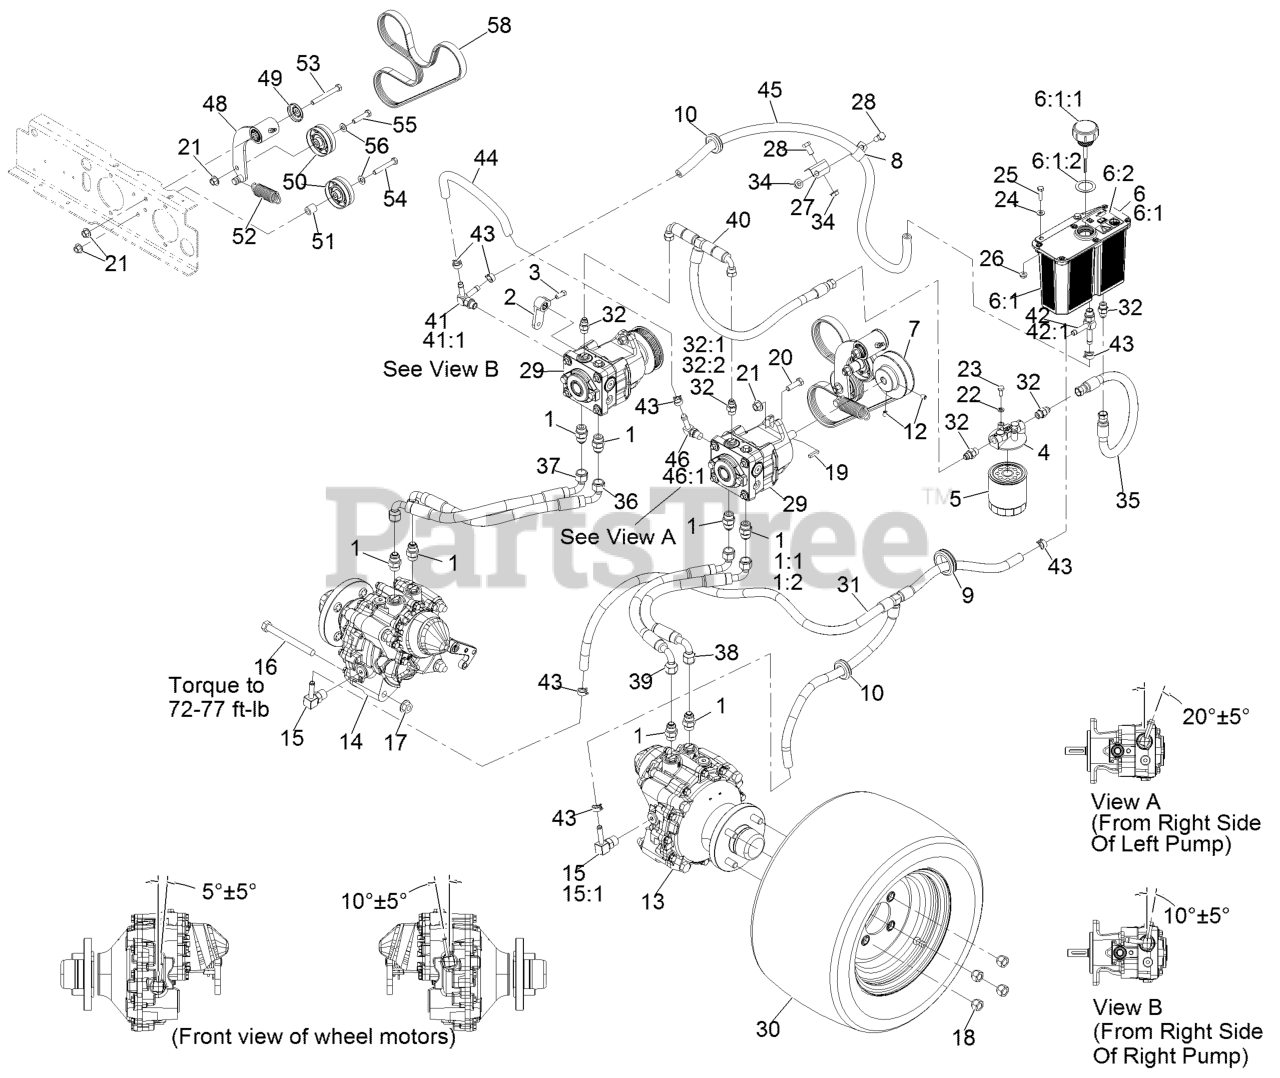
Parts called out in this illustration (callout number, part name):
1	FITTING-STRAIGHT
2	ARM-CONTROL, PUMP
3	SCREW-SET, SQH
4	HEAD-FILTER
5	FILTER-25 MICRON, BI-DIRE
6	RESERVOIR ASM
6:1	Reservoir-HYD
6:1:1	RESERVOIR CAP ASM
6:1:2	GASKET-CAP
6:2	DECAL-WARNING
8	CLIP-LOOM
9	GROMMET
10	GROMMET
12	SCREW-SET
13	MOTOR-HYD, LH
14	MOTOR-HYD, RH
15	FITTING-90
15:1	O-RING
16	SCREW-HH
17	NUT-HHF
18	NUT-LUG
20	SCREW-HH
21	NUT-FLANGE
22	WASHER-LOCK
23	SCREW-HH
24	WASHER-FLAT
25	SCREW-HH
27	BRACKET-CLAMP
28	SCREW-HH
29	12CC HYDRO PUMP ASM
30	TIRE AND WHEEL ASM
31	HYDRAULIC HOSE ASM
32	FITTING-STRAIGHT
34	NUT-HHF, WHIZ
35	HYDRAULIC HOSE ASM
36	HYDRAULIC HOSE ASM
37	HYDRAULIC HOSE ASM
38	HYDRAULIC HOSE ASM
39	HYDRAULIC HOSE ASM
40	HYDRAULIC HOSE ASM
41	ADAPTER-TEE
41:1	O-RING
42	ADAPTER-RUN, TEE
42:1	O-RING
43	CLAMP-HOSE
44	HOSE-HYD
45	HOSE-HYD
46	FITTING-ELBOW, 90
46:1	O-RING
48	IDLER ASM
49	GUARD-TOP
51	SPACER-MOUNTING, STEERING
52	SPRING-IDLER
53	SCREW-HH
54	SCREW-HH
55	SCREW-HH
56	WASHER-FLAT
58	BELT-V
